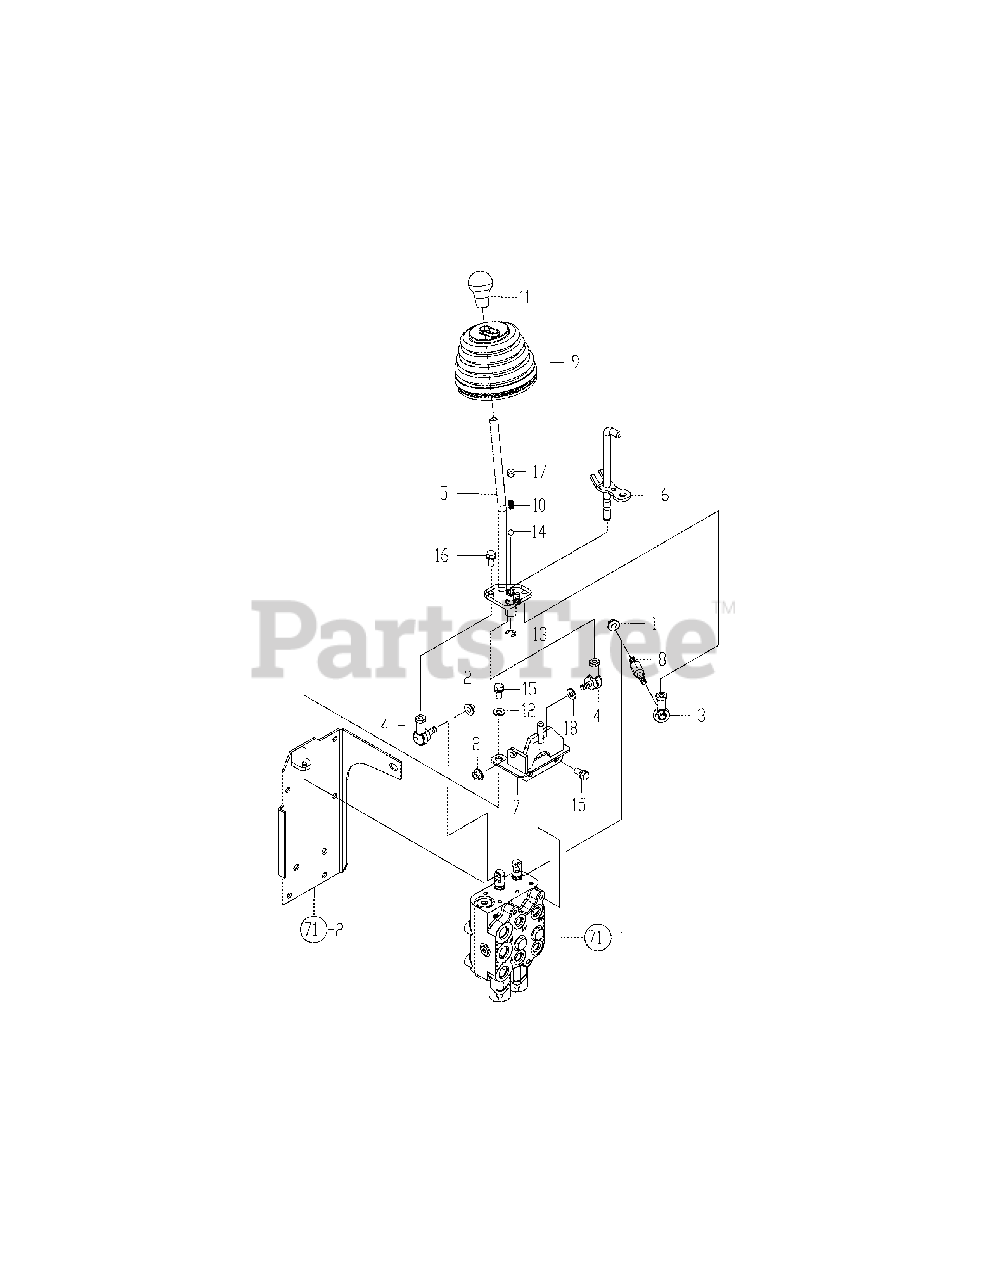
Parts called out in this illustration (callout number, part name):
7	Bkt Cmp, Scv Lever
8	Bolt,Scv Lever
9	Boots,Scv Lever
17	Screw, 10 X 10
